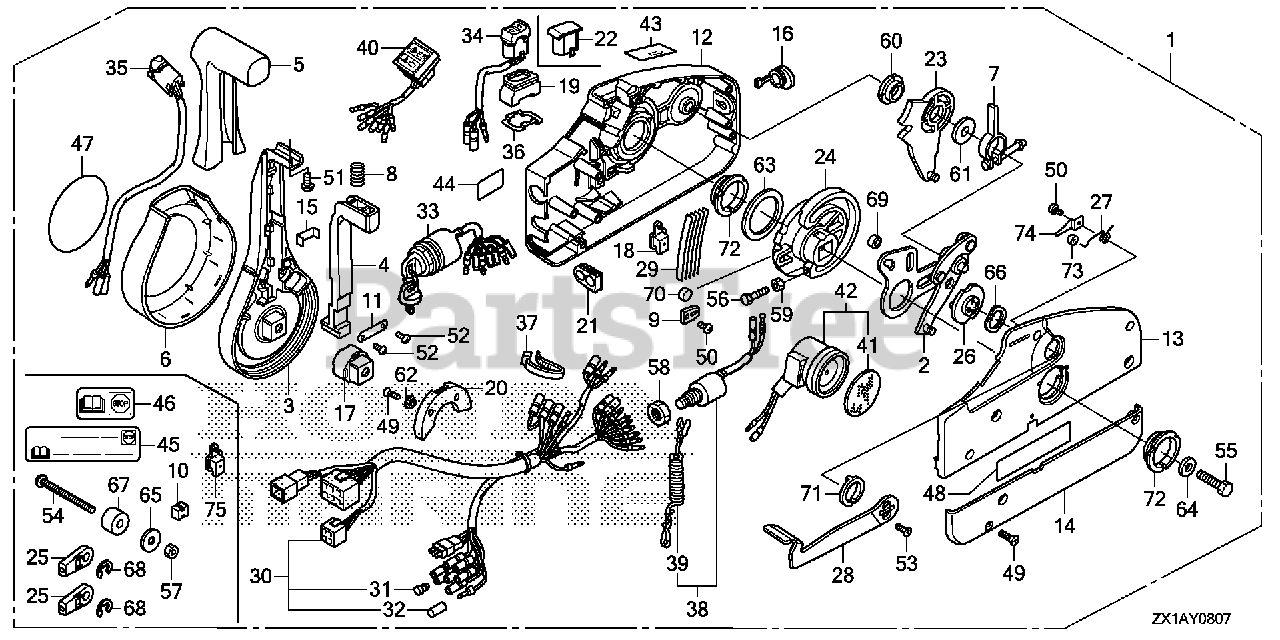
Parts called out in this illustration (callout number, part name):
1	BOX ASSY., REMOTE CONTROL (NHK MEC)
1	BOX ASSY., REMOTE CONTROL (4-LED) (NHK MEC)
1	BOX ASSY., REMOTE CONTROL (TROLLING CONTROL)(NHK MEC)
2	PLATE ASSY.
3	LEVER, HAND
4	ARM, NEUTRAL LOCK
5	GRIP
6	COVER, LEVER
7	ARM ASSY., BRAKE
8	SPRING (2)
9	CLIP, DETENT
10	SPACER (1) (LOOSE PARTS)
11	BRACKET
12	HOUSING, FR.
13	HOUSING, RR.
14	PANEL, BACK
15	BRACKET, WIRE CLAMP
16	CAP, RUBBER
17	ADJUSTER
18	COVER, POWER TRIM-TILT WIRE (LOOSE PARTS)
19	SEAL, RUBBER
20	HOLDER, NEUTRAL LOCK
21	GROMMET, WIRE (14)
22	CAP, TROLLING CONTROL SWITCH BLANK
23	GEAR ASSY., SHIFT
24	GEAR, DRIVE
25	TERMINAL, CABLE (LOOSE PARTS)
26	DRUM ASSY., FREE THROTTLE
27	SPRING (1)
28	LEVER, FREE THROTTLE
29	SPRING, DETENT
30	CABLE ASSY., REMOTE CONTROL (B)
30	CABLE ASSY., REMOTE CONTROL (B)(TROLLING CONTROL)
31	PLUG, CONNECTOR (INNER) (TROLLING CONTROL)
32	PLUG, CONNECTOR (OUTER) (ENGINE NO.)
33	SWITCH ASSY., COMBINATION (SINGLE) (DUAL)
34	SWITCH ASSY., TROLLING CONTROL
35	SWITCH ASSY., POWER TRIM-TILT
36	PLATE, SWITCH
37	BAND, WIRE
38	SWITCH ASSY., EMERGENCY STOP
39	WIRE, EMERGENCY (SINGLE) (DUAL)
40	LAMP ASSY., INDICATION
41	PLATE, TURN SIGNAL BUZZER DUAL QTY = (2) (SINGLE)
42	BUZZER, WARNING DUAL QTY = (2) (SINGLE)
43	MARK, FAST IDLE
44	MARK, EMERGENCY STOP (US) (LOOSE PARTS)
45	MARK, EMERGENCY STOP (US) (LOOSE PARTS)
47	MARK, EMBLEM
48	LABEL, SIGP
49	SCREW (5X18)
50	SCREW (4X6)
51	SCREW (5X10)
52	SCREW (4X10)
53	SCREW (5X12)
54	SCREW (6X90) (LOOSE PARTS)
55	BOLT (8X50)
56	BOLT (5X25)
57	NUT (6MM) (LOOSE PARTS)
58	NUT, HEX. (16MM) DUAL QTY = (2) (SINGLE)
59	NUT (5MM)
60	BEARING (1)
61	WASHER (3)
62	WASHER (4)
63	WASHER (5)
64	WASHER (8MM)
65	WASHER (7) (LOOSE PARTS)
66	WASHER, WAVE
67	SPACER (2) (LOOSE PARTS)
68	E-RING (6MM) (LOOSE PARTS)
69	ROLLER, DRIVE GEAR CAM
70	ROLLER
71	BEARING (2)
72	BEARING (3)
73	ROLLER, FREE THROTTLE
74	CLIP, ROLLER
75	COVER, POWER TRIM-TILT WIRE (LOOSE PARTS)
